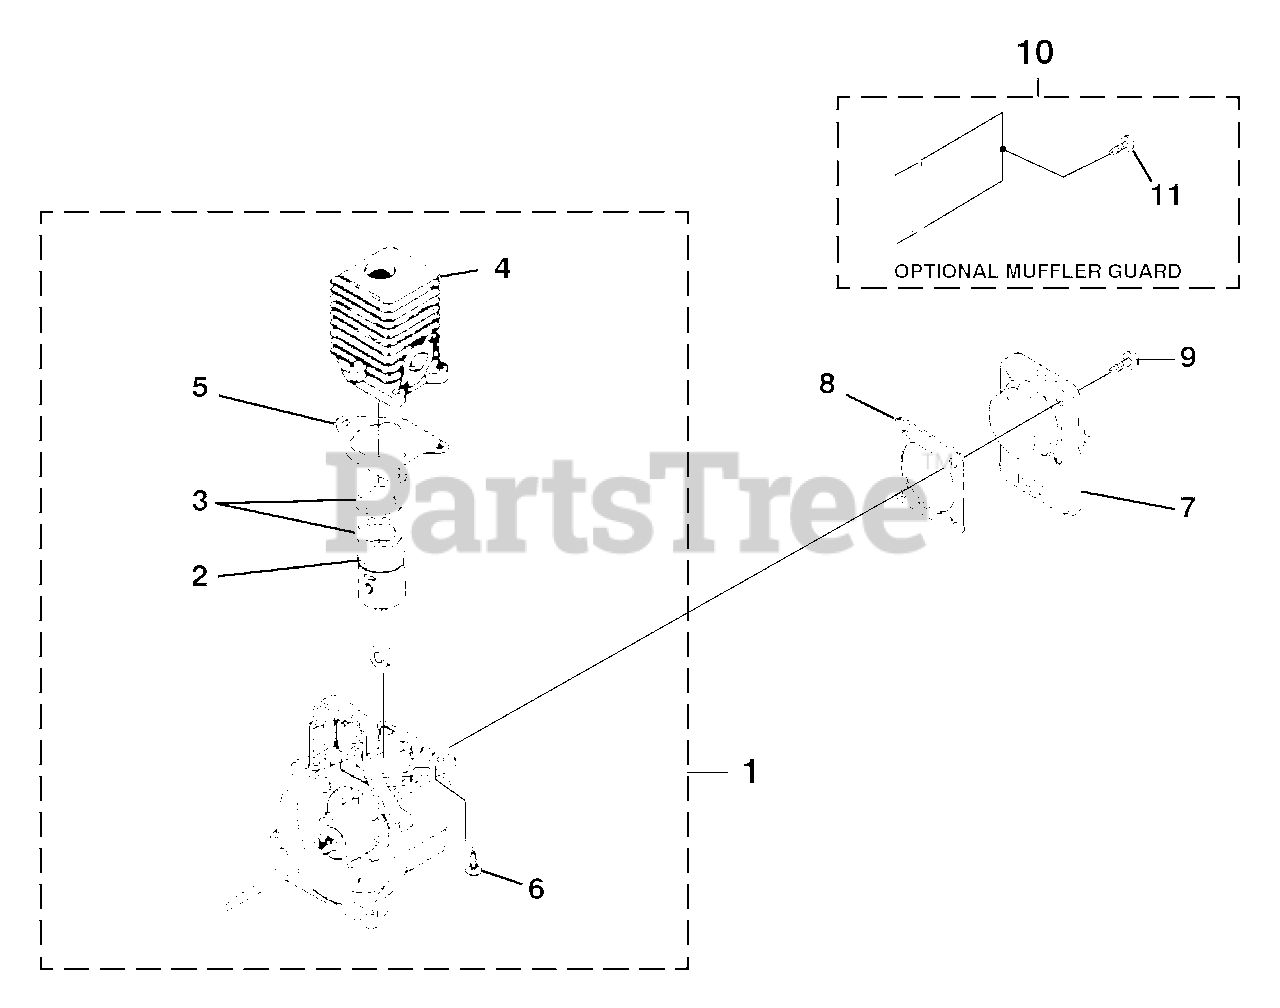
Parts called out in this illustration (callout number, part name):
1	SHORT BLOCK SSY.
2	PISTON & ROD ASSY.
3	RING- Piston
4	CYLINDER
5	GASKET Cylinder
6	SCREW-Sems (12-24 X 3/4")
7	CRANKCASE COVER
8	GASKET Crankcase Cover
9	SCREW- Sems (10-24 X 1/2")
10	MUFFLER GUARD
11	SCREW- Plasite (10-14 X 1/2")
